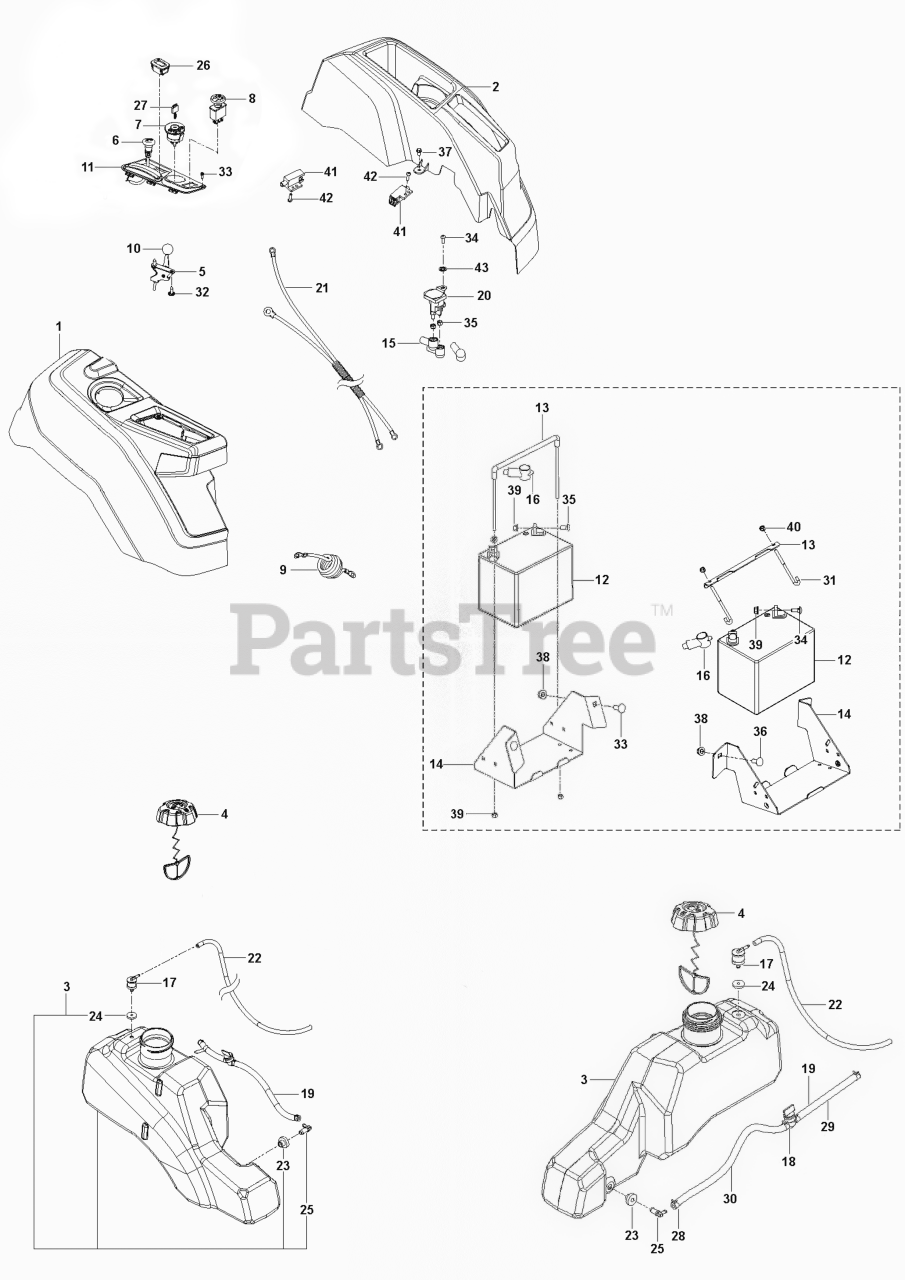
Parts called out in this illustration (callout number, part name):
1	CONSOLE.ASSY.RZ.REFRESH.RH
2	CONSOLE.LH.ASM
3	TANK.ASM3"NECK.NOCAP.NOSHDRZ17
4	CAP ASSY FUEL 3" GRAY
4	FUEL CAP
5	THROTTLE CONTROL W/BALL KNOB
5	CABLE.THROTTLE.37"
5	THROTTLE CABLE
6	CHOKE.PUSH-IN.STYLE
6	CHOKE.PUSH-IN.STYLE.57"
7	RP IGNITION SWITCH
8	RP SWITCH.PTO.TERMINAL.STD.RED
9	CABLE BATTERY POS RZ
10	KNOB.ROUND.BALL.BLACK
11	CONTROL.PANEL.RZ.REFRESH.RH
12	BATTERY, 12 V 300 AMP DRY
12	BATTERY, 12 V 330 AMP
13	BATTERY TIE DOWN ASSEMBLY
13	BRACKET.PNT.MOUNT.BATTERY.EDIP
14	BOX BATTERY RZ BLACK
14	BOX.PNT.BATTERY.RZ.EDIP
15	TERMINAL COVER
15	COVER.TERMINAL.RED
17	VALVE.FUEL.CHECK
18	FUEL VALVE
19	FUEL.HOSE.SHUT.OFF.ASM.10".18"
19	FUEL.HOSE.SHUT.OFF.ASM.10".3"
20	SOLENOID.STARTER.BRASS.PLUNGER
21	HARNESS.BTTRY.CABLE.RZ.REFRESH
22	HOSE.3/16".VAPOR.LINE.33"LGTH
22	HOSE.3/16".VAPOR.LINE.64"LGTH
22	HOSE.3/16".VAPOR.LINE.18"LGTH
22	HOSE.3/16".VAPOR.LINE.50"LGTH
22	HOSE.3/16".VAPOR.LINE.23"LGTH
23	BUSHING OUTLET T
24	GROMMET.ROV.SENTEC
25	STEM FUEL TANK
26	GUAGE.SRVCMNDR.HRMTR.
27	KEY MLD GEN DELTA
28	HOSE CLAMP
29	HOSE.1/4".LOW.PERM.FUEL.LN.10"
30	HOSE 1/4" LOW PERMEATION FUEL
31	HOOK.J.BATTERY
32	HOOK.J.BATTERY
32	SCREW.PAN.HEAD.#10
33	SCREW 6-19X.437
34	SCR 1/4-20 X 5/8 BTN SKT HD ZD
35	RP BOLT 5/16-18 X3/4 ZN/YEL GR
36	RHSNB 3/8C X 1
37	Screws
37	LOCKNUT.NYLOC.1/4-20
38	RHSNB 3/8C X 1
38	NUT 3/8-16 HEX FLG NYLOC ZD
39	5/16-18 NYLOC FLANGE NUT
40	NUT.1/4-20.HEX.NYLOC.ZD
40	NUT.CROWNLOCK.1/4
40	LOCKNUT.NYLOC.1/4-20
41	SWITCH.INTLK.RZ.RFRSH.BUTTON
42	RHSNB 3/8C X 1
42	SCREW.BUTTONHD.10-24X1/2.(2 2)
42	SCR #10-24 X .75 SKT HD BLK
43	WASHER 1/4 INT TOOTH
